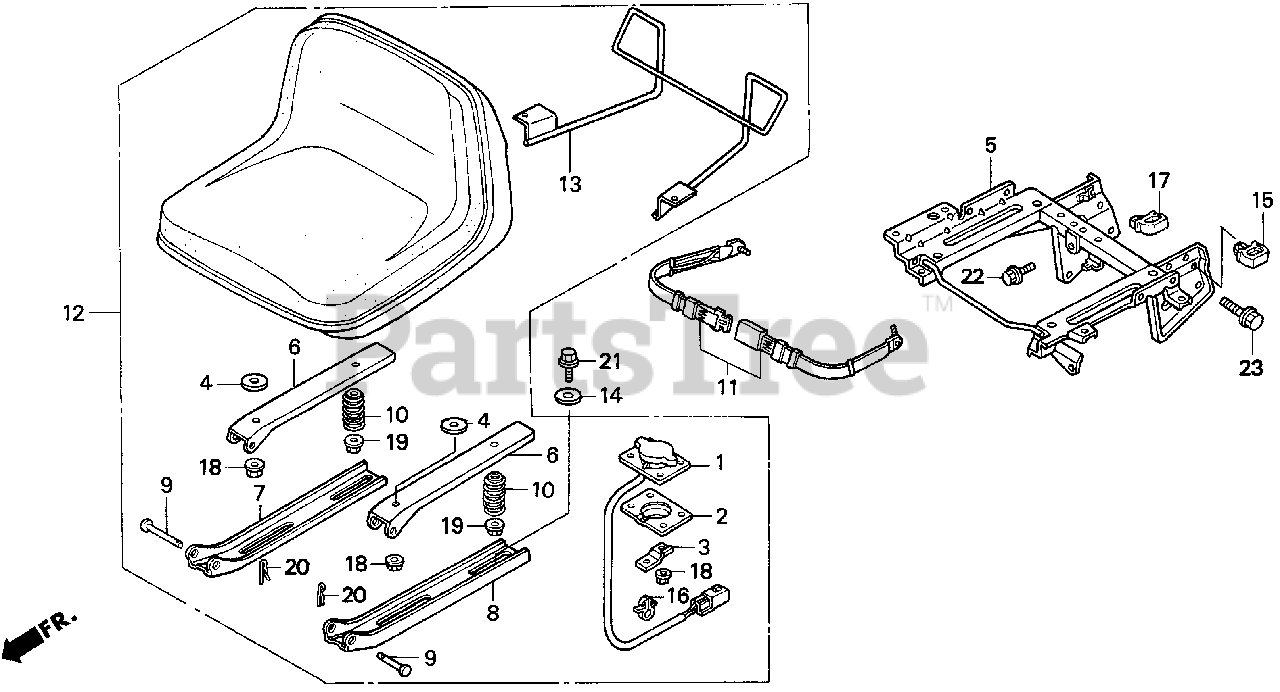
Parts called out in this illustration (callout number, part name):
1	SWITCH, SEAT
2	COVER, SEAT SWITCH
3	BASE, CLIP
4	WASHER (5MM)
5	FRAME, SEAT SUPPORT
6	BASE, SEAT (UPPER)
7	BASE, R. SEAT (LOWER)
8	BASE, L. SEAT (LOWER)
9	PIN, SEAT BASE (8MM)
10	SPRING, SEAT
11	SEAT BELT ASSY.
12	SEAT ASSY.
13	HOLDER, TOOL BOX
14	WASHER, ROTOR SETTING
15	CLIP, HARNESS (15MM) (BLUE)
16	CLIP, WIRE HARNESS (6MM) (WHITE)
17	CLIP, WIRE HARNESS
18	NUT, FLANGE (6MM)
19	NUT-WASHER (6MM)
20	PIN, LOCK (8MM)
21	BOLT, FLANGE (8X16)
22	BOLT, FLANGE (8X20)
23	BOLT, FLANGE (10X25)
